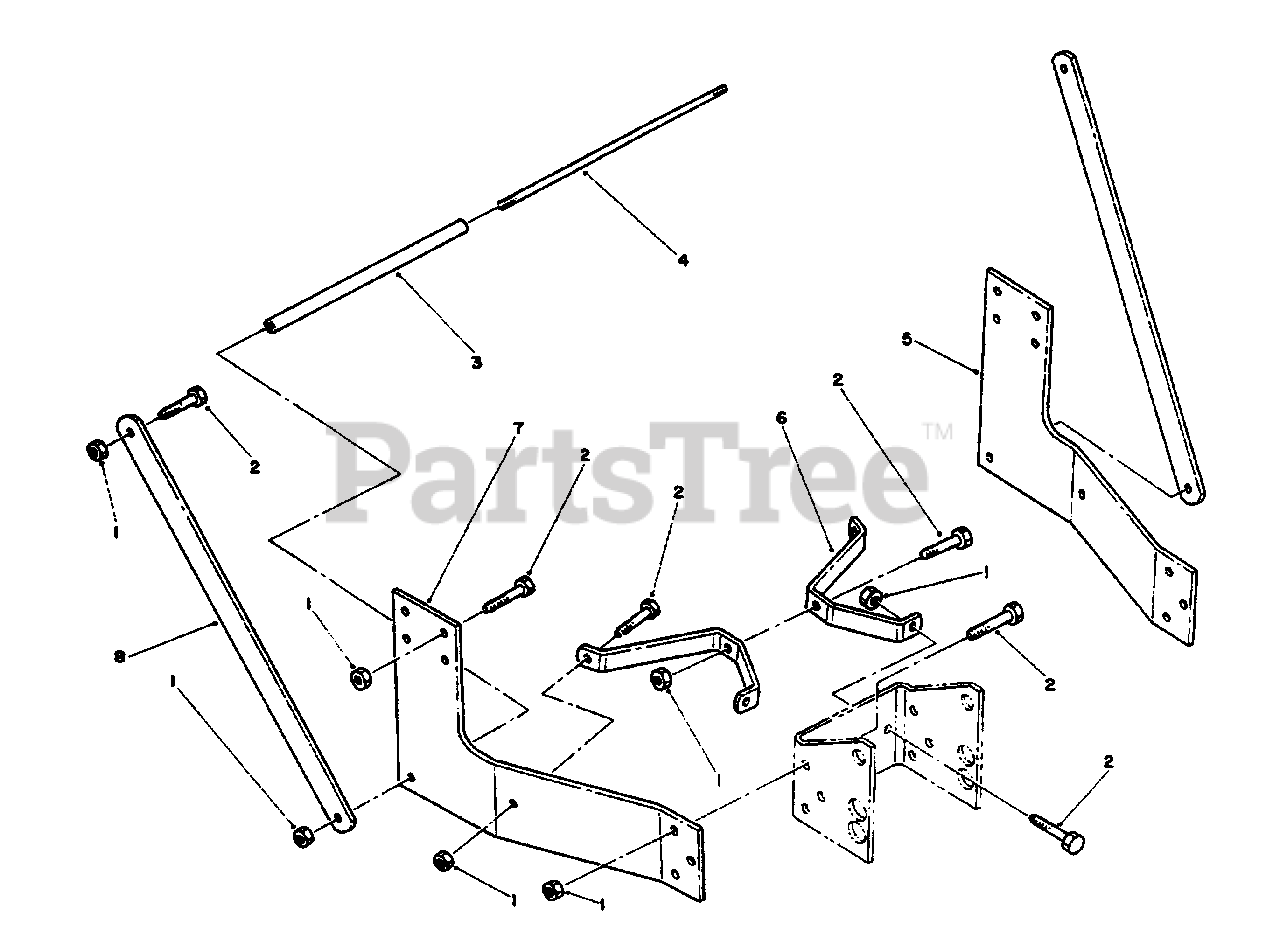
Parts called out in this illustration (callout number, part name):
1	Nut-Lock
2	Screw-Hex Hd. Cap
3	Tube-support
4	Rod-Support
5	Bracket-LH.
6	Brace-Center
7	Bracket R.H.
8	Brace
